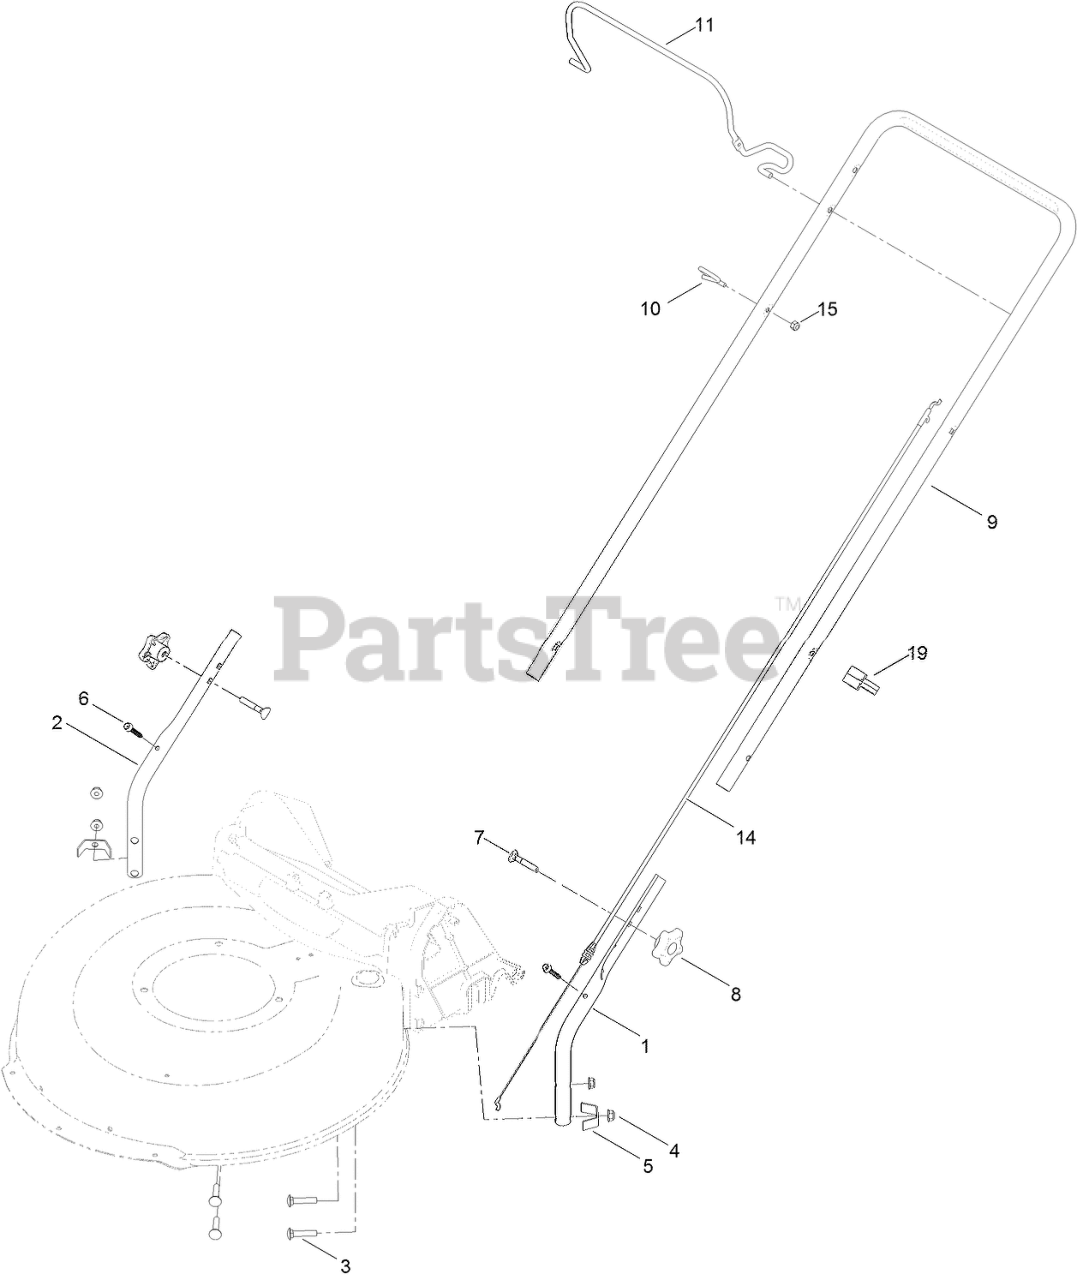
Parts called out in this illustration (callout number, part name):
1	HANDLE-LOWER, LH
2	HANDLE-LOWER, RH
3	BOLT-CARR
4	NUT-FLANGE, NI
5	BRACKET-CHUTE
6	SCREW-FLANGE, SERRATED
7	SCREW-HANDLE
8	KNOB-HANDLE
9	HANDLE-UPPER
10	GUIDE-ROPE
11	BAIL-BRAKE
14	CABLE-BRAKE, ENGINE
15	NUT-LOCK, NI
19	GUIDE-CABLE
